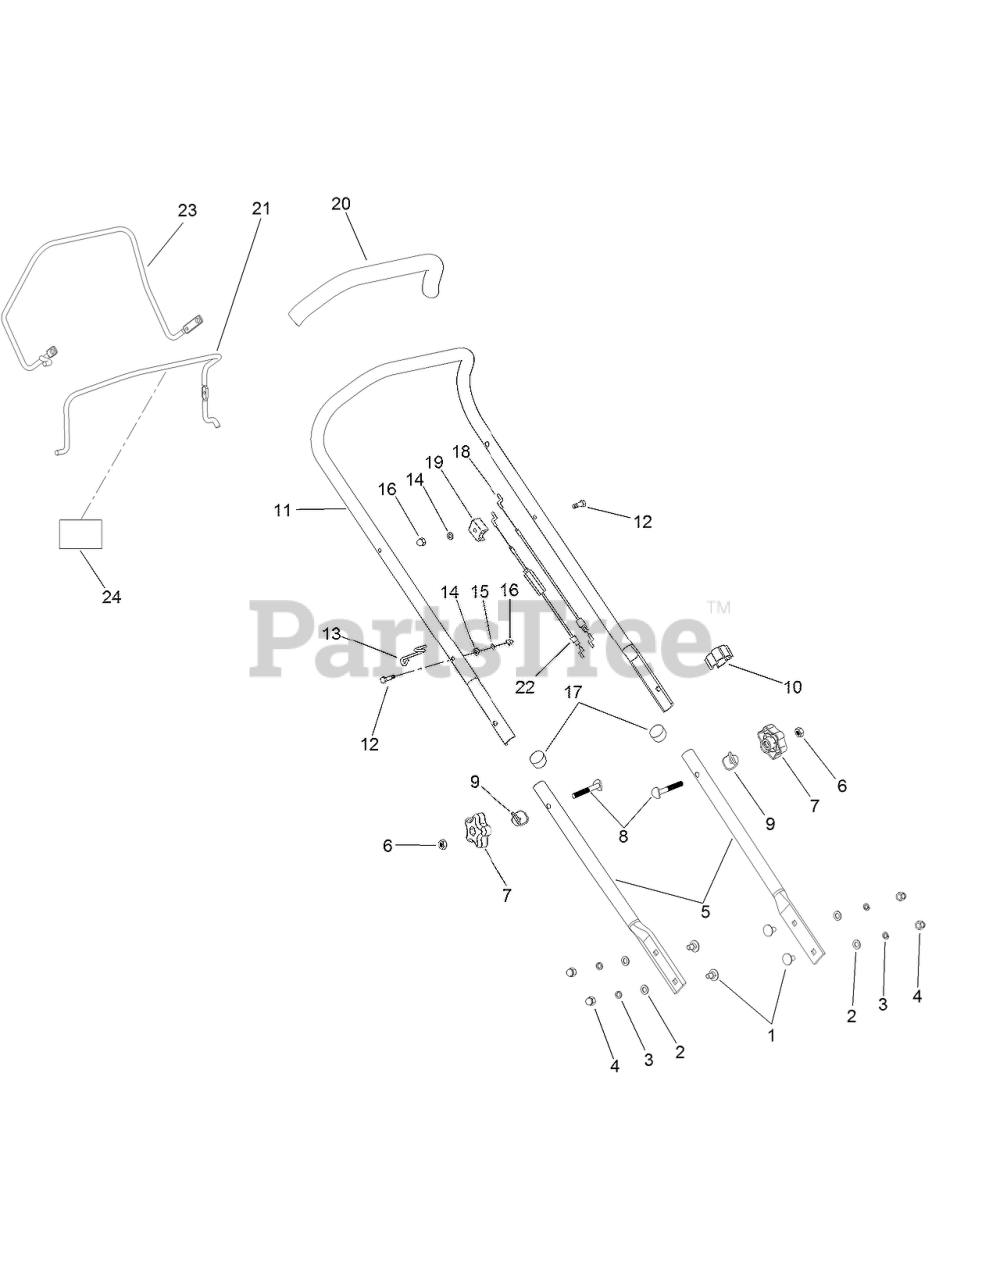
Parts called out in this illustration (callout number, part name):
2	WASHER
3	WASHER-SPRING
4	NUT-LID
5	RAIL-GRAB, LOWER
6	NUT-HEX
7	KNOB-ROTARY, LOWER RAIL
8	BOLT-FLAT HEAD
9	WASHER-CURVE
10	CABLE CLAMP
11	RAIL-GRAB, UPPER
12	BOLT-HH, FLANGE
13	HOOK-CABLE
14	WASHER-PLAIN
15	WASHER-SPRING
16	NUT-LID
17	PLUG-TUBE
18	FRAMEOUT CORD ASM
19	CABLE-BLOCK, FIXED
20	GRIP-HANDLE
21	ROD-FRAMEOUT
22	DRIVING CORD ASM
23	ROD-DRIVE
24	DECAL-STOP
